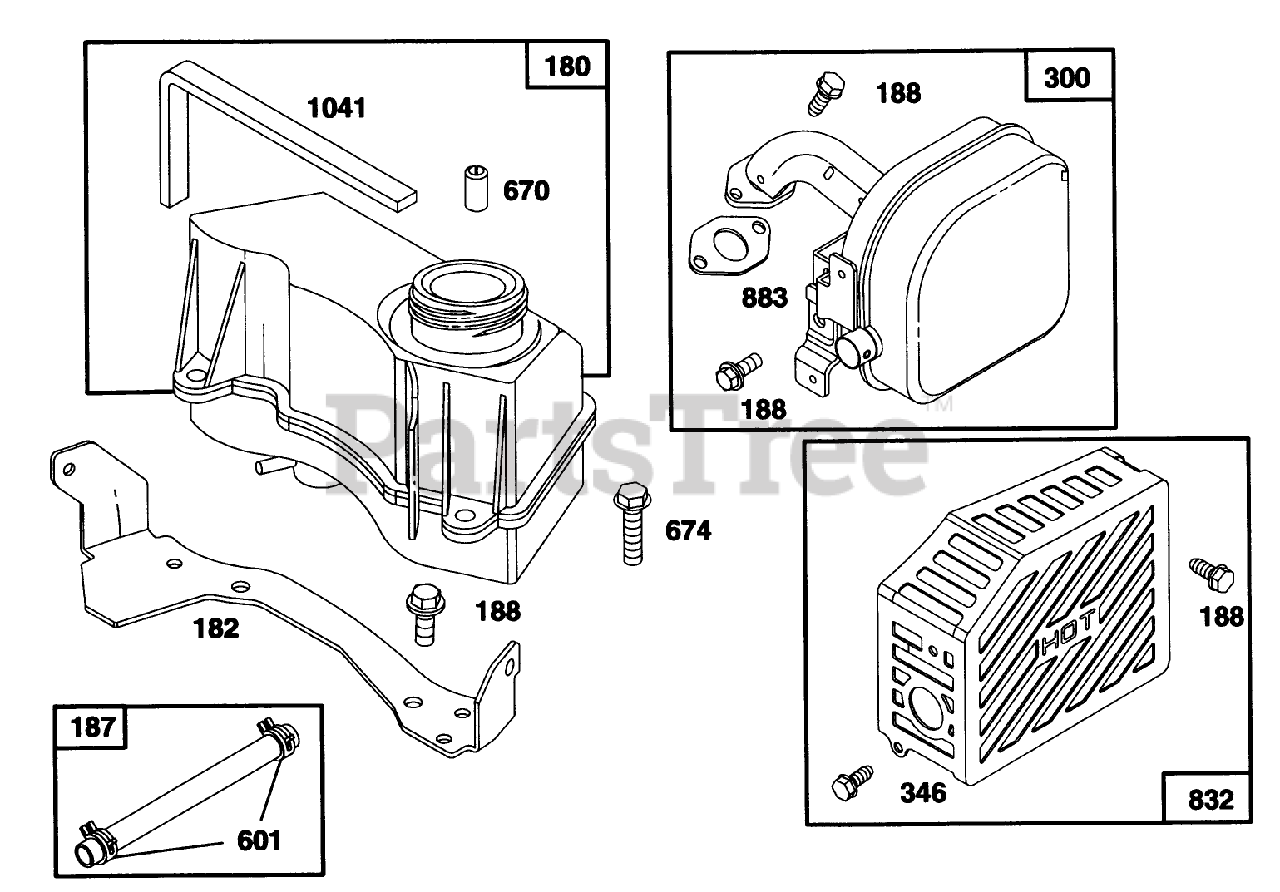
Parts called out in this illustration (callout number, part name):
180	TANK ASSY - FUEL
187	BRIGGS 296004
300	MUFFLER - EXHAUST
670	SPACER
674	SCREW - HEX HEAD
